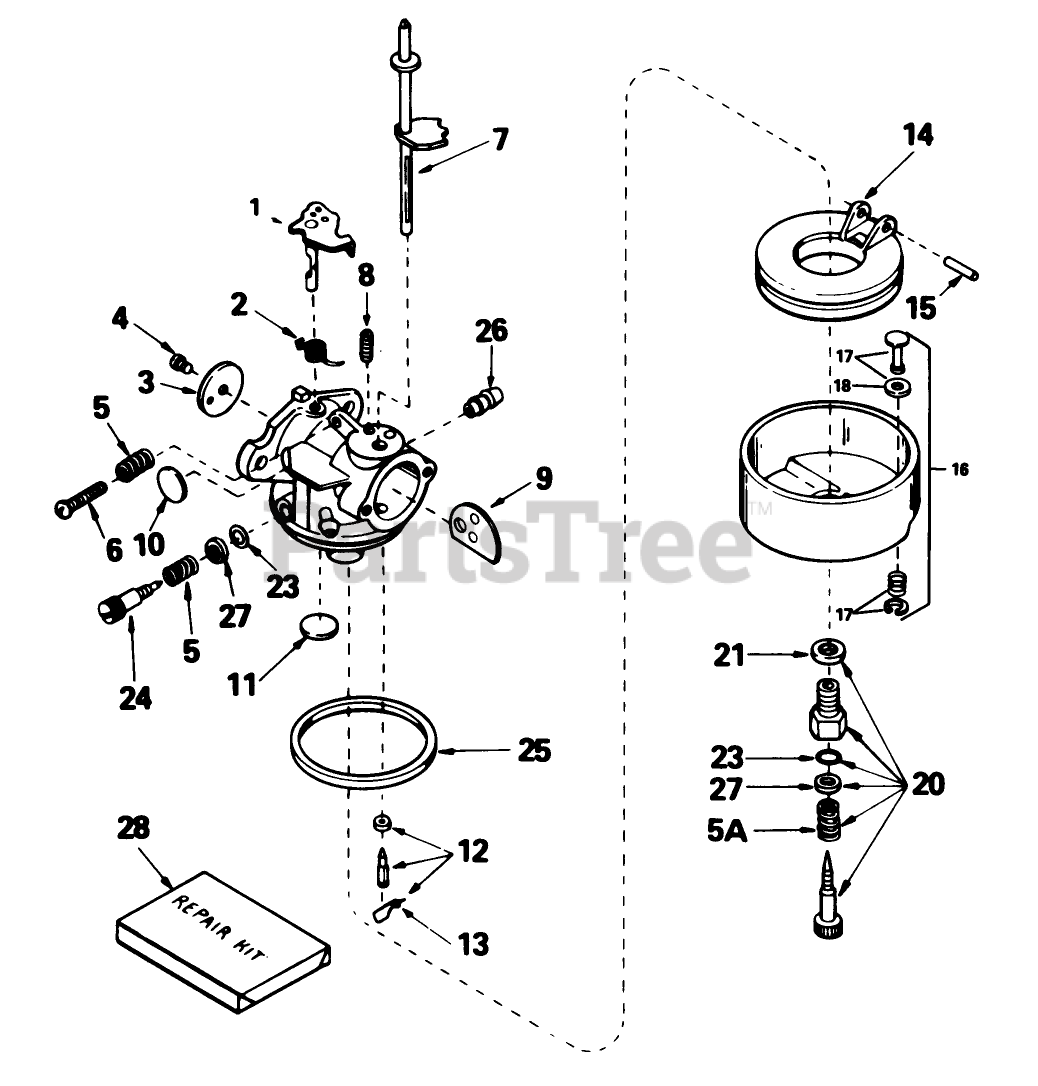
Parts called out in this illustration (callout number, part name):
1	Shaft/Lever-Throttle
2	Spring-Return, Throttle
3	Shutter-Throttle
4	Screw-Shutter
5	Spring-Tension
5A	Spring
6	Screw-Throttle Crack Screw / Idle Speed
7	Shaft-Choke
8	Spring-Positioning, Choke
9	Shutter-Choke
10	Plug-Welch, Idle Mixture Well
11	Plug-Welch, Atmospheric Vent
12	Inlet Needle, Seat Clip Assy. (Incl. No. 13)
13	Clip-Spring
14	Float
15	Shaft-Float
16	Float Bowl Asm. (Incl. Ref. # 32, 33)
17	Bowl Drain ASM
18	Gasket-Plunger, Drain
20	Adjustment Screw Assy., Main (Incl. Nos. 5A, 21 23)
21	Washer-Bowl Nut
23	ORing
24	Screw-Idle
25	O Ring-Bowl, Float
26	Fitting-Fuel
27	Washer
28	Repair Kit (Incl. items marked *)
